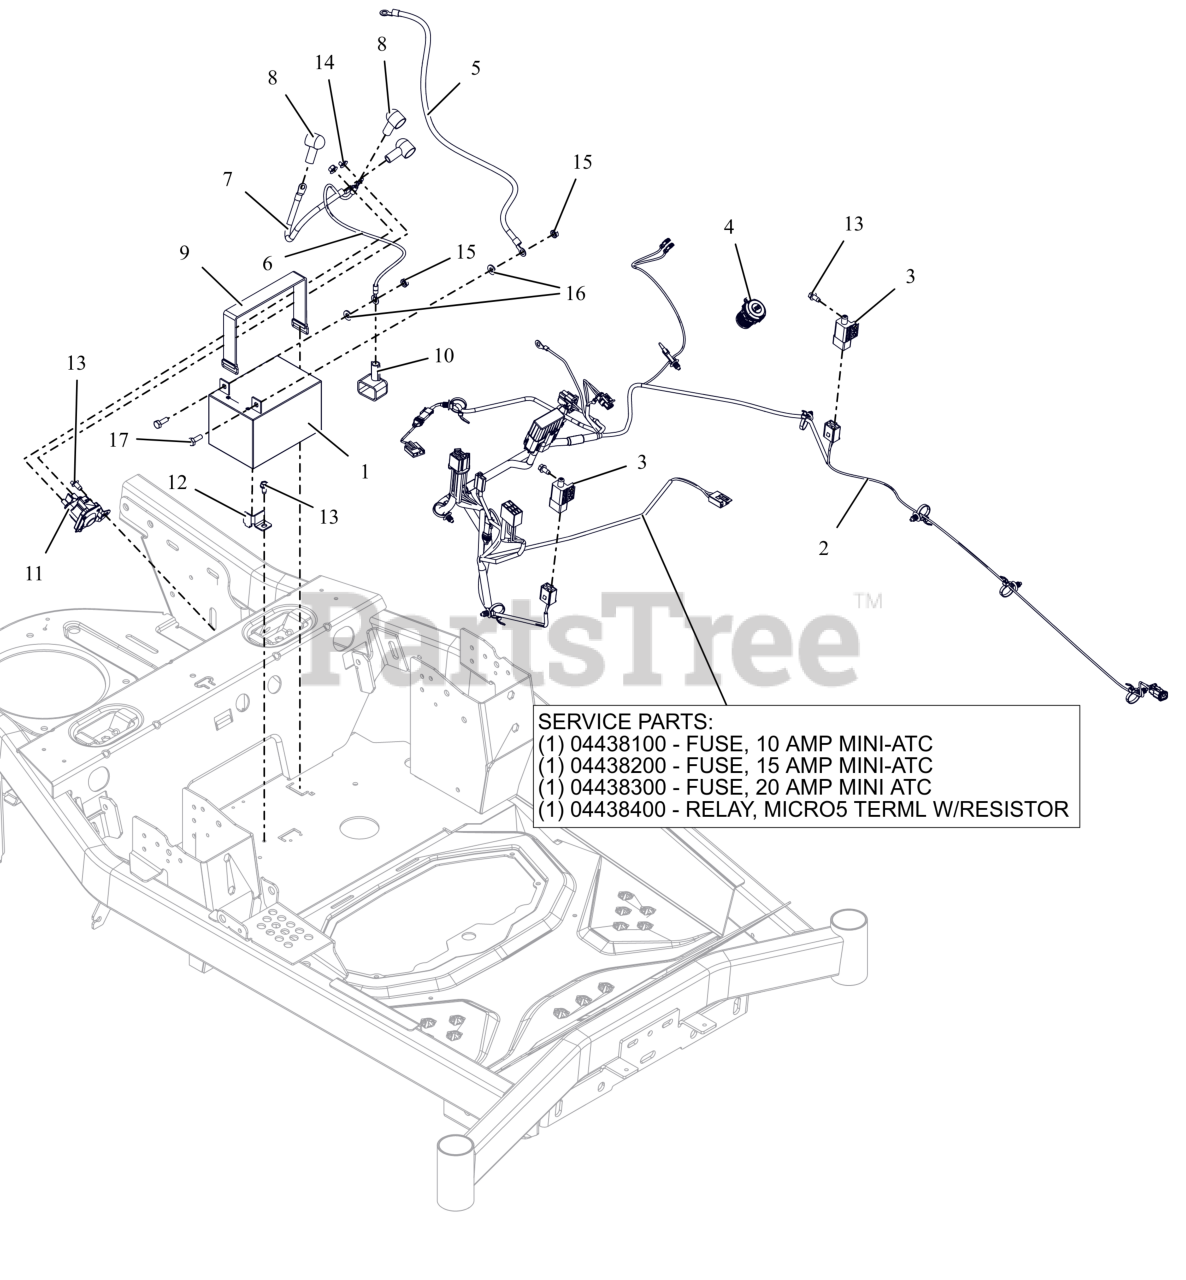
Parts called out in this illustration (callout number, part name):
1	BATTERY, 12V 12A -190CCA
2	HARNESS- MAIN- IKON23
2	FUSE,10 AMP MINI-ATC
2	Fuse, 15 AMP MINI-ATC
2	FUSE,20 AMP MINI ATC
2	RELAY,MICRO5 TERML W/RESISTOR
3	SWITCH-BRAKE NO/NO-POST & HOLE
4	USB, DUAL PORT USB-C, 12V BLK
5	CABLE-NEGATIVE BATTERY 24.00"
6	CABLE,POS W/2 1/4 RING 18.5 LG
7	CABLE, POS W/(2)1/4 RING 9.0LG
8	BOOT, EYELET TERMINAL
9	STRAP- RUBBER
10	INSULATOR
11	SOLENOID, STARTER (SEALED)
12	RETAINER, BATTERY CORNER (BLACK)
13	SCR-TAP .25-20X.50 HWH ZCC
14	NUT- M6-1.0 W/ CONICAL WASHER
15	NUT-KEPS .250-20 ZCC
16	WSHR,FLT .281X.625X.065 ZCC
17	BLT, HEX .25-20X.75 G5 ZCC
